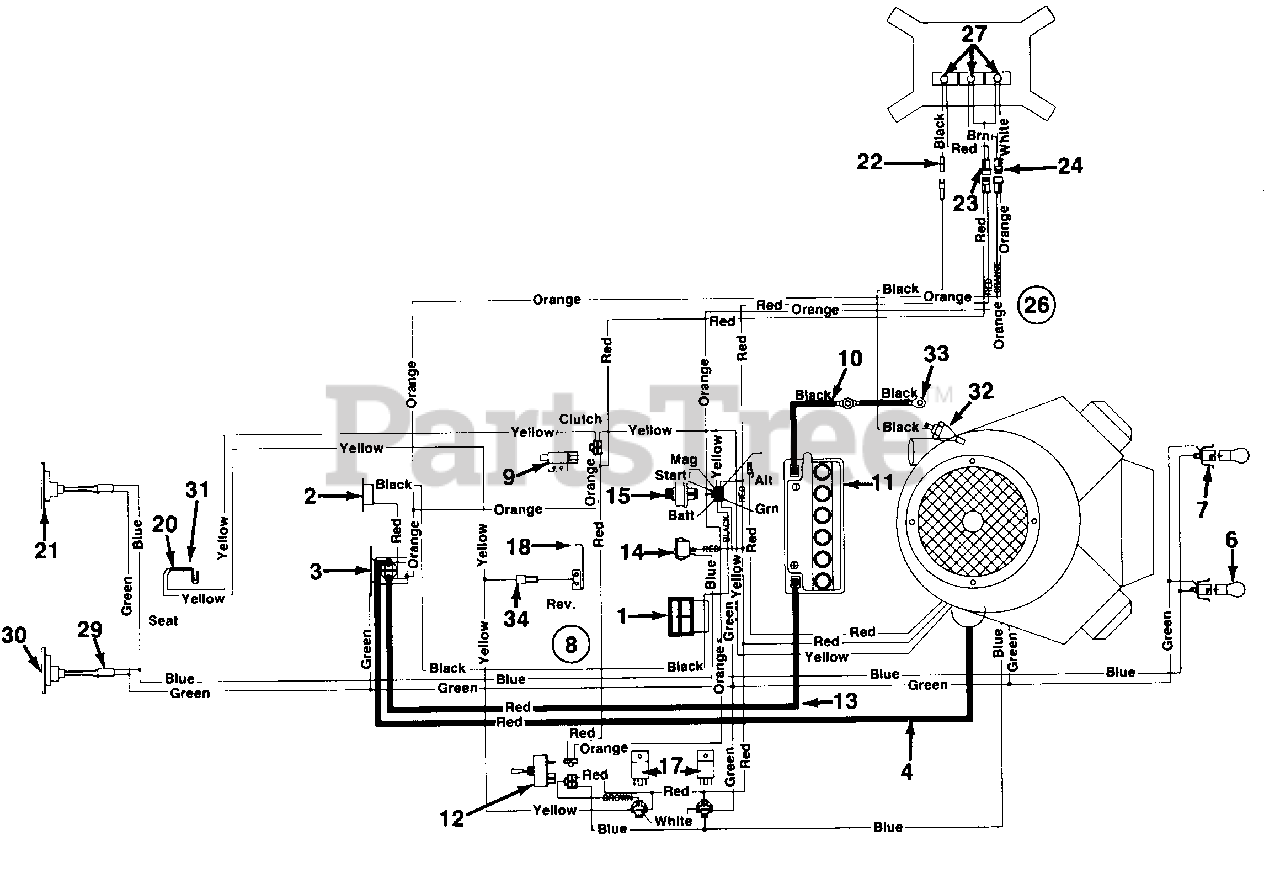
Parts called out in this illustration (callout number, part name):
1	Ammeter
2	Circuit Breaker
3	Solenoid
4	Wire 30" Lg.
6	Bulb
7	Socket
8	Wire Harness
9	Safety Switch (Clutch)
10	6 Ga. Black Wire
11	Battery 12V (275 Cold Crank Amps)
12	Switch (PTO)
13	Wire 27" Lg.
14	Light Switch
15	Ignition Switch
17	Relay
18	Spring Lever
20	Safety Switch (Seat)
21	Taillight
22	Connector
23	Connector
24	Connector
26	Wire Harness
27	Bulb
29	Taillight Harness
31	Safety Switch (Seat)
32	Oil Pressure Switch
33	Wire 7.5" Lg.
34	Extension Wire
